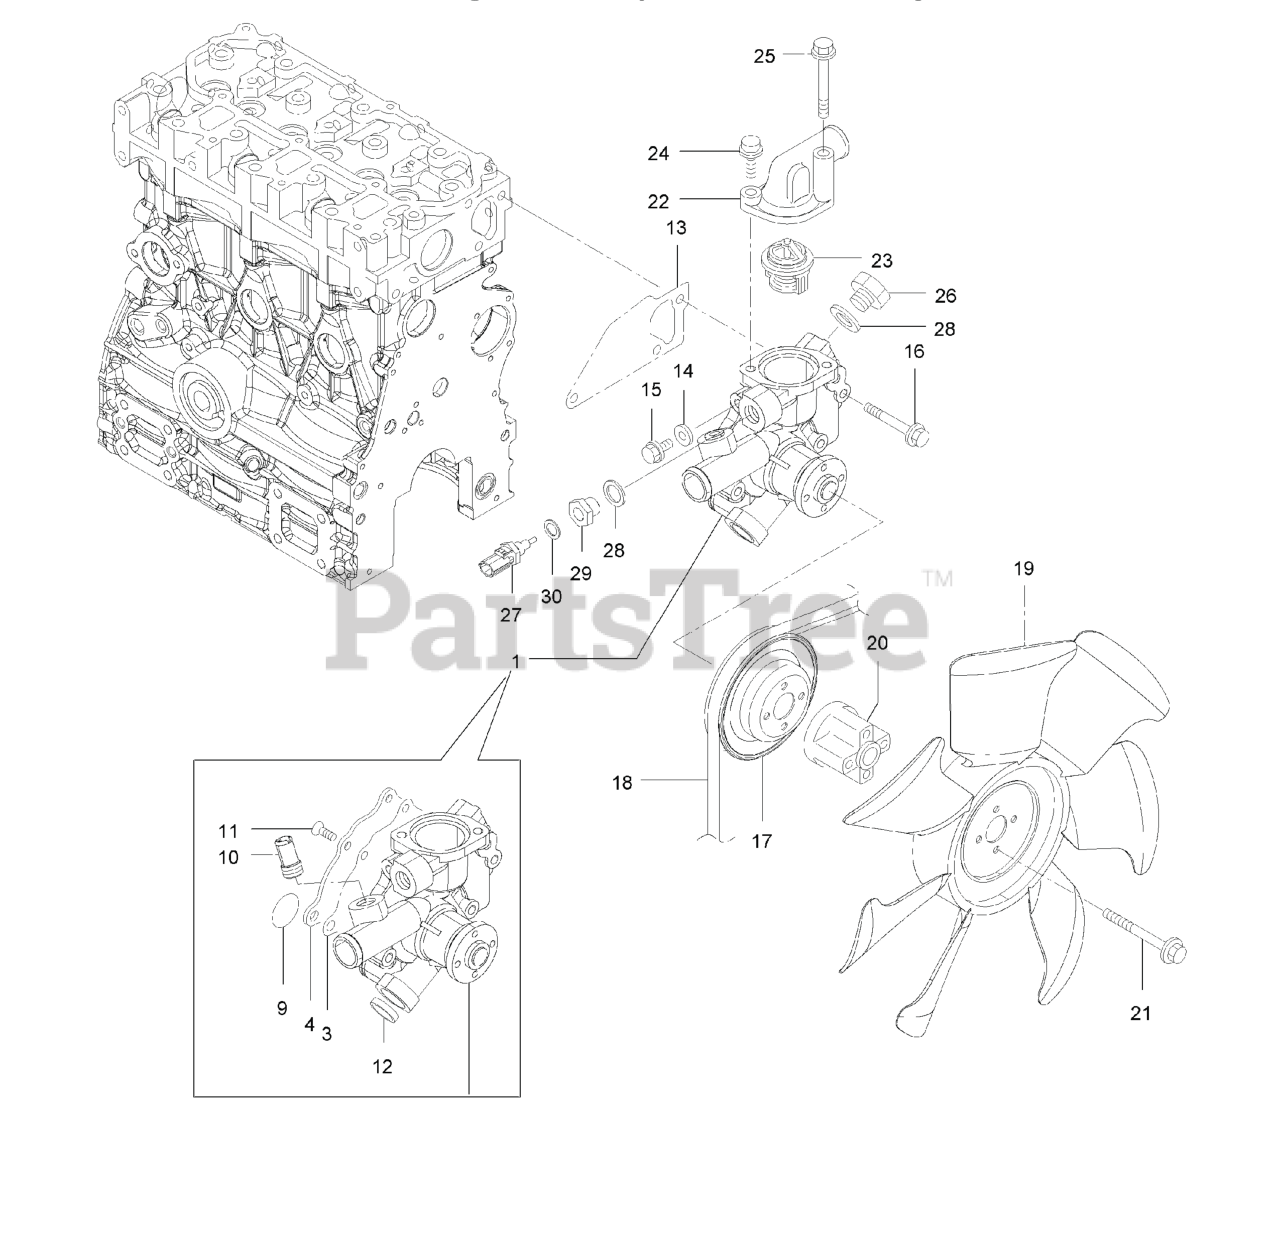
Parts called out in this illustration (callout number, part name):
1	PUMP ASM-WATER
10	JOINT-PIPE
13	GASKET-WATER PUMP
17	V-PULLEY
19	FAN-COOLING 1
20	SPACER-FAN
22	COVER-THERMOSTAT
23	THERMOSTAT
27	SENSOR-THERMOSTAT, CW
30	WASHER-SEAL
